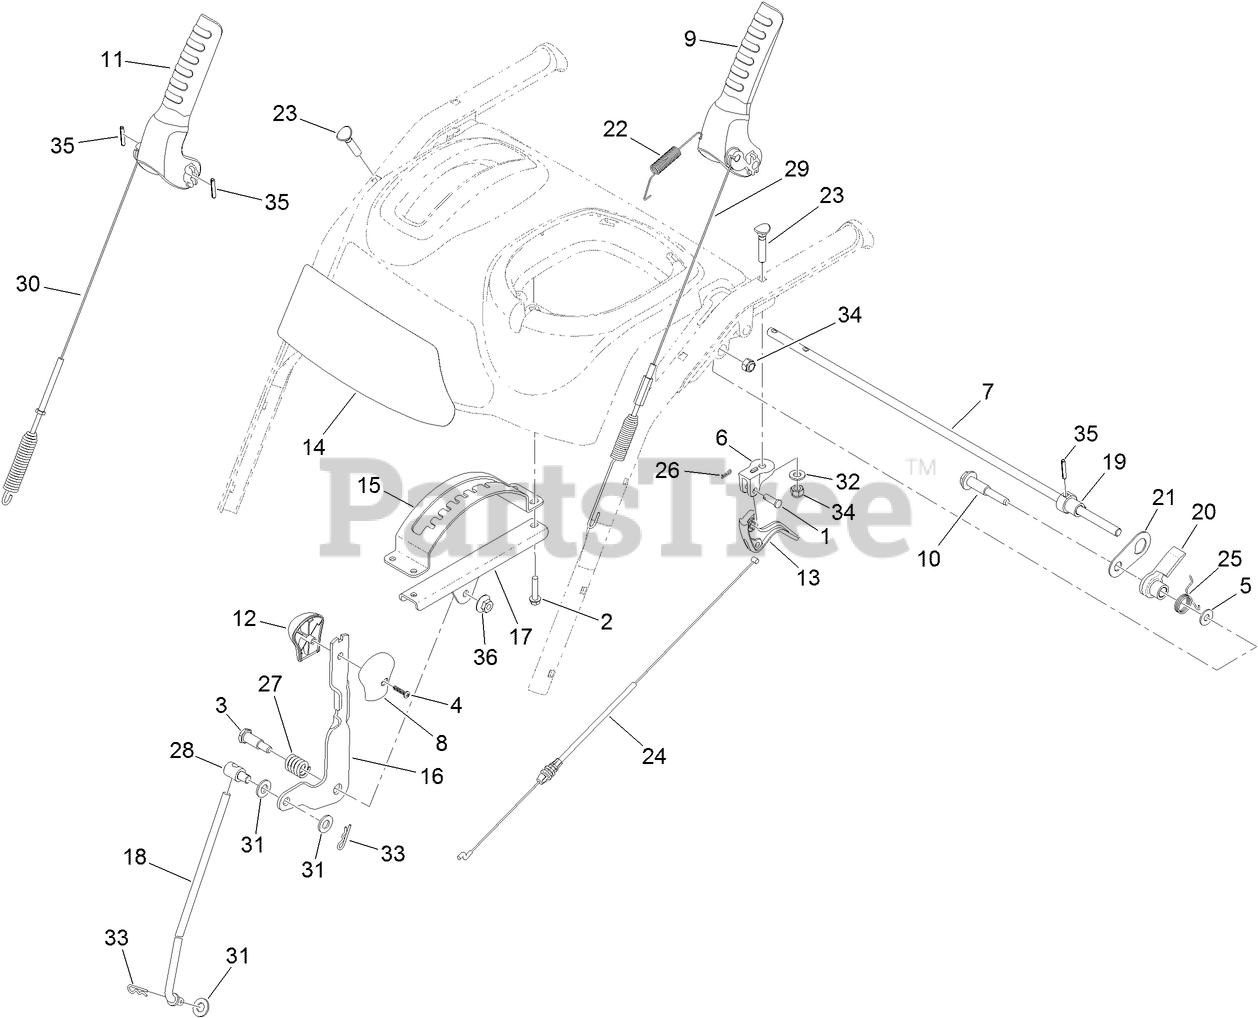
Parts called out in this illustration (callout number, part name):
1	PIN-CLEVIS
2	SCREW-PLASTITE
3	SCREW-SHOULDER
4	SCREW-PPH
5	WASHER-FLAT
6	MOUNT-LEVER, CLUTCH
7	ROD-LOCKOUT
8	KNOB-SHIFT, LH
9	LEVER-TRACTION
11	LEVER-AUGER
12	KNOB-SHIFT, RH
13	LEVER-CLUTCH
15	GUIDE-SELECTOR, SPEED
16	SELECTOR-SPEED
17	MOUNT-SELECTOR, SPEED
19	CAM-LOCKOUT
20	LATCH-LOCKOUT
21	LINK-LOCKOUT
22	SPRING-TENSION
23	SCREW-HANDLE
24	CABLE-CLUTCH
25	SPRING-TORSION
26	PIN-HAIR
28	TRUNNION-ROD
29	CABLE-TRACTION
30	CABLE-AUGER
31	WASHER-FLAT
32	WASHER-FLAT
34	NUT-LOCK, NI
35	PIN-SPRING
36	NUT-HF
